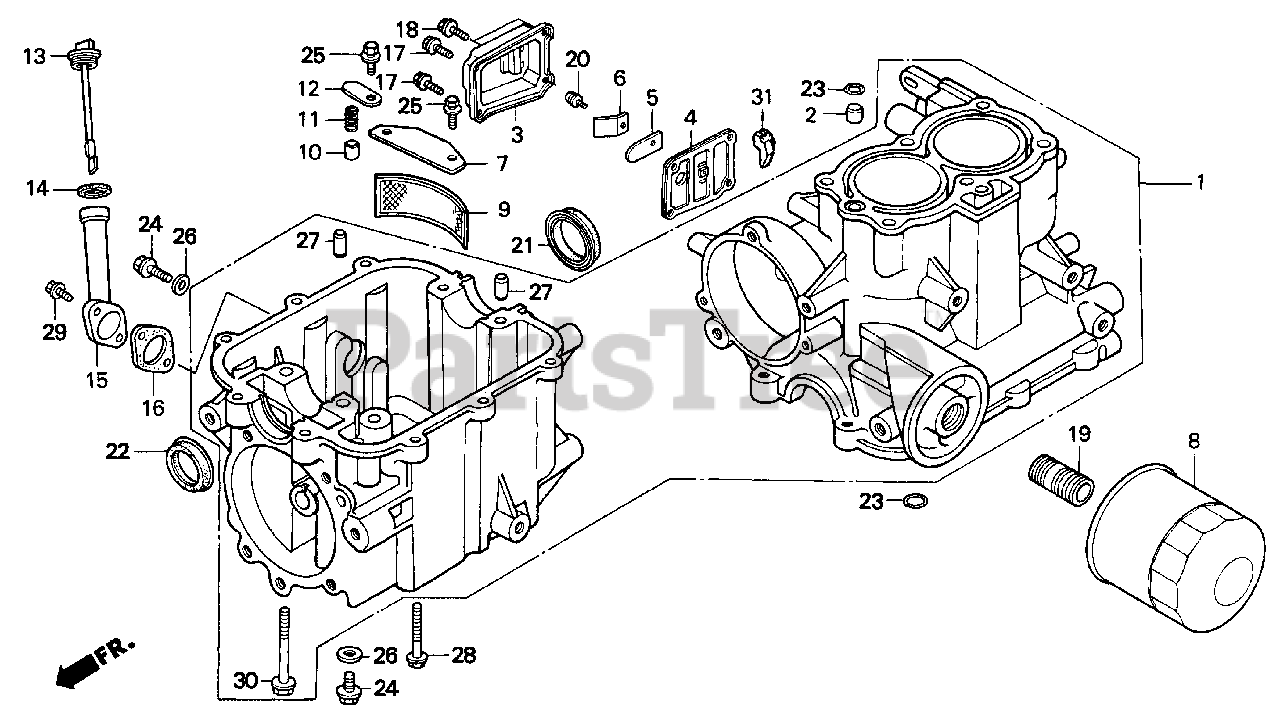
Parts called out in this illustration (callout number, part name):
1	CYLINDER ASSY.
2	ORIFICE, OIL CONTROL
3	COVER, BREATHER
4	PLATE, BREATHER
5	PLATE, VALVE
6	STOPPER, VALVE
7	PLATE, OIL FILTER
8	FILTER, OIL
8	FILTER, OIL (TOYO ROKI)
9	SCREEN, OIL FILTER
10	VALVE, CHECK
11	SPRING, VALVE
12	PLATE, VALVE
13	CAP, OIL FILLER
14	GASKET, OIL FILLER CAP
15	PIPE, OIL FILLER
16	GASKET, OIL PIPE
17	BOLT, FLANGE (6X12) (CT200)
17	BOLT, FLANGE (6X14)
18	BOLT, FLANGE (6X14)
19	PIPE, OIL PASSAGE
20	SCREW-WASHER (5X8)
21	OIL SEAL (33X48X7)
22	OIL SEAL (30X44X7)
23	O-RING (10.8X2.4) (ARAI)
24	BOLT, DRAIN PLUG (12MM)
25	BOLT-WASHER (6X12)
26	WASHER, DRAIN PLUG (12MM)
27	PIN A, DOWEL (10X16)
28	BOLT, FLANGE (6X28)
29	BOLT, FLANGE (6X20)
30	BOLT, FLANGE (8X55)
